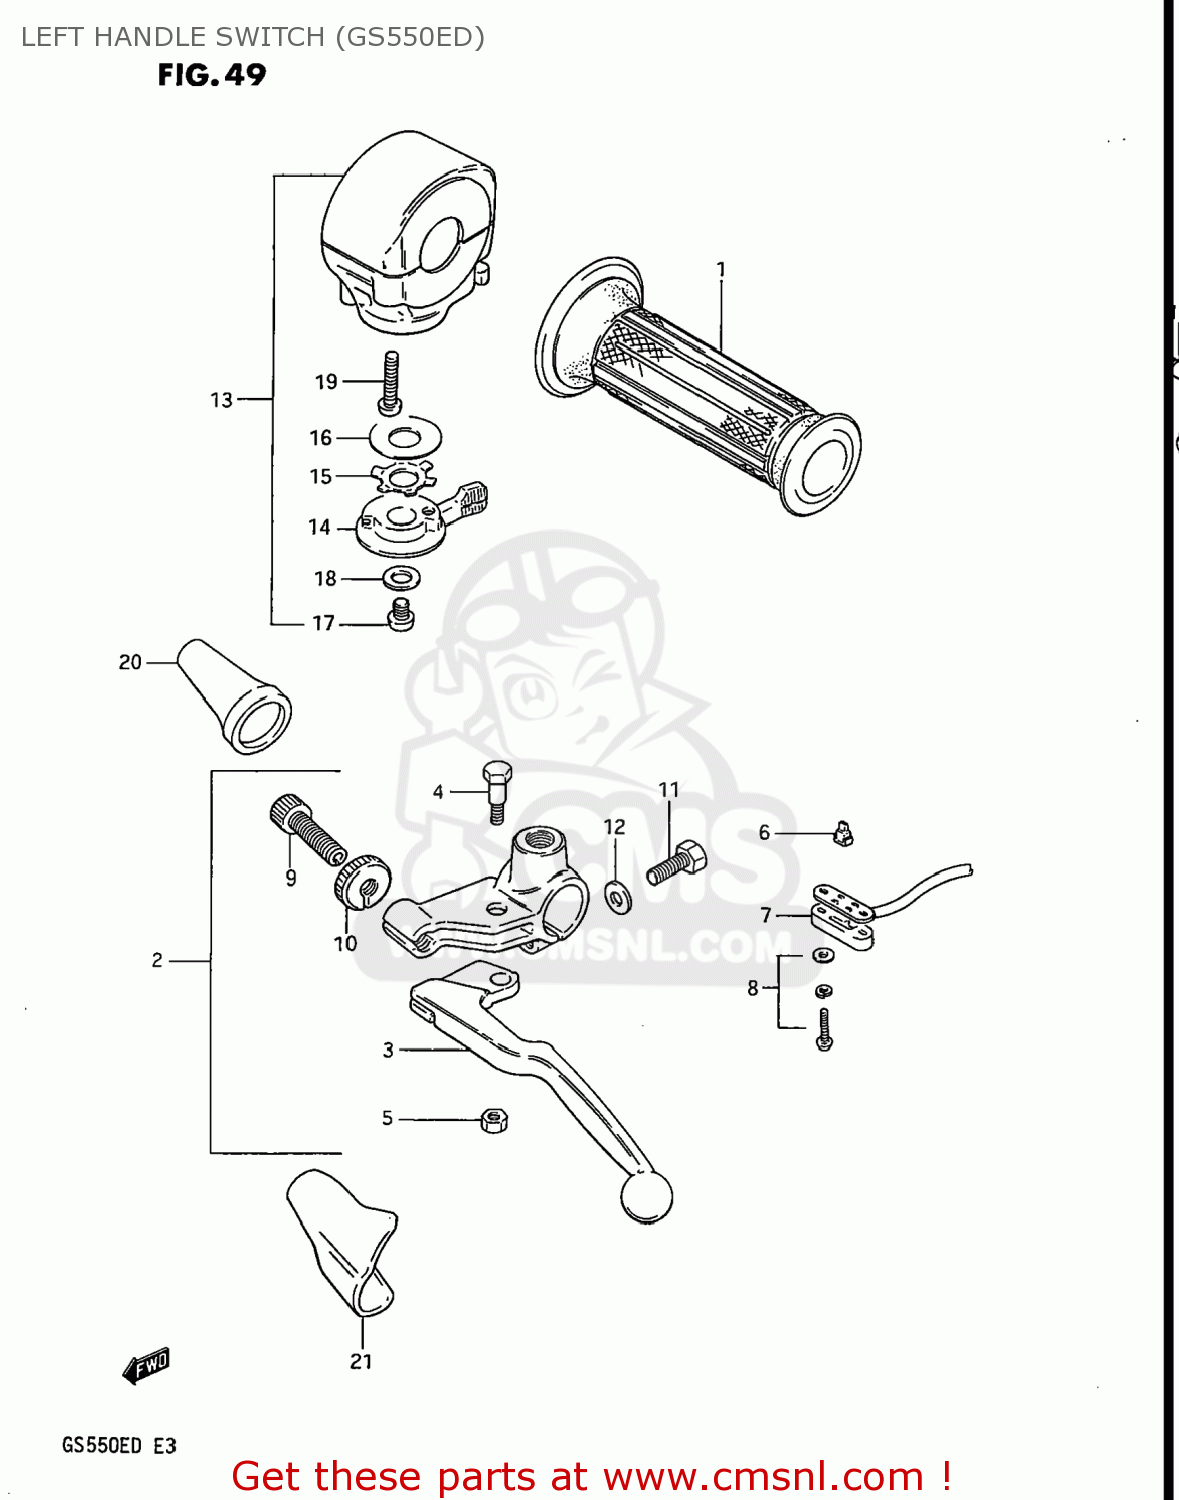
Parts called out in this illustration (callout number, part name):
1	GRIP,L
2	LEVER ASSY,CLUTCH
3	LEVER,CLUTCH
4	BOLT,LEVER
5	NUT 6MM
6	CONTACT,SWITCH
7	COVER,FR BK TERMINAL BASE
8	SCREW
9	ADJUSTER,CABLE
10	NUT,CABLE ADJUSTER LOCK
11	BOLT,CLUTCH LEVER HOLDER
12	SPACER
13	SWITCH ASSEMBLY,HANDLE,LEFT
14	LEVER,STARTER
15	WASHER
16	WASHER
17	SCREW
18	WASHER 6MM
19	SCREW
20	BOOT,CLUTCH CABLE
21	COVER,CLUTCH LEVER
